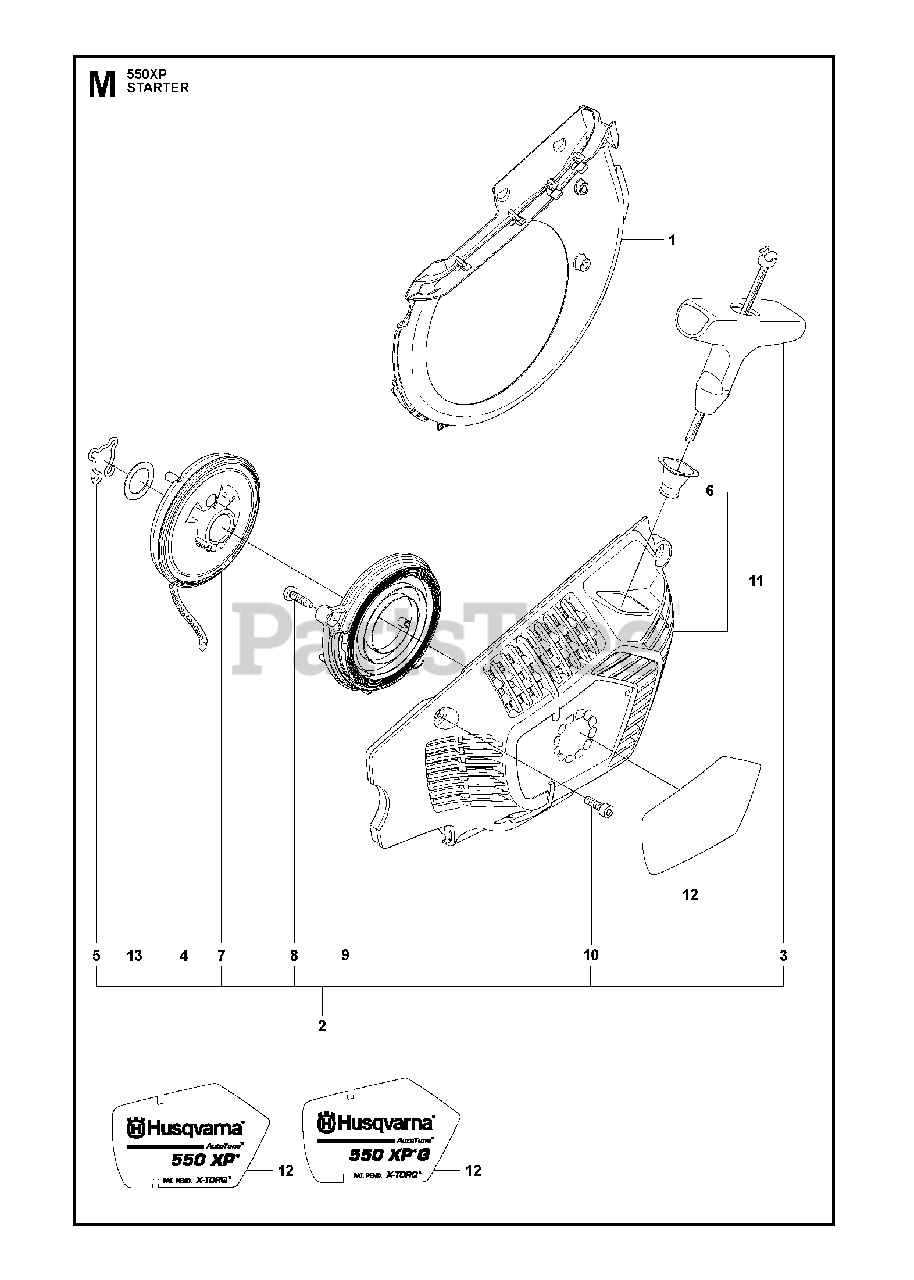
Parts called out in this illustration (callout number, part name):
1	COOLING AIR CONDUCTOR
2	STARTER ASSY
3	HANDLE
4	STARTER ROPE
5	CLIPS
6	SLEEVE
7	STARTER PULLEY ASSY
8	SCREW
9	SPRING CASSETTE ASSY
10	SCREW
11	STARTER HOUSING
12	LABEL
13	WASHER
